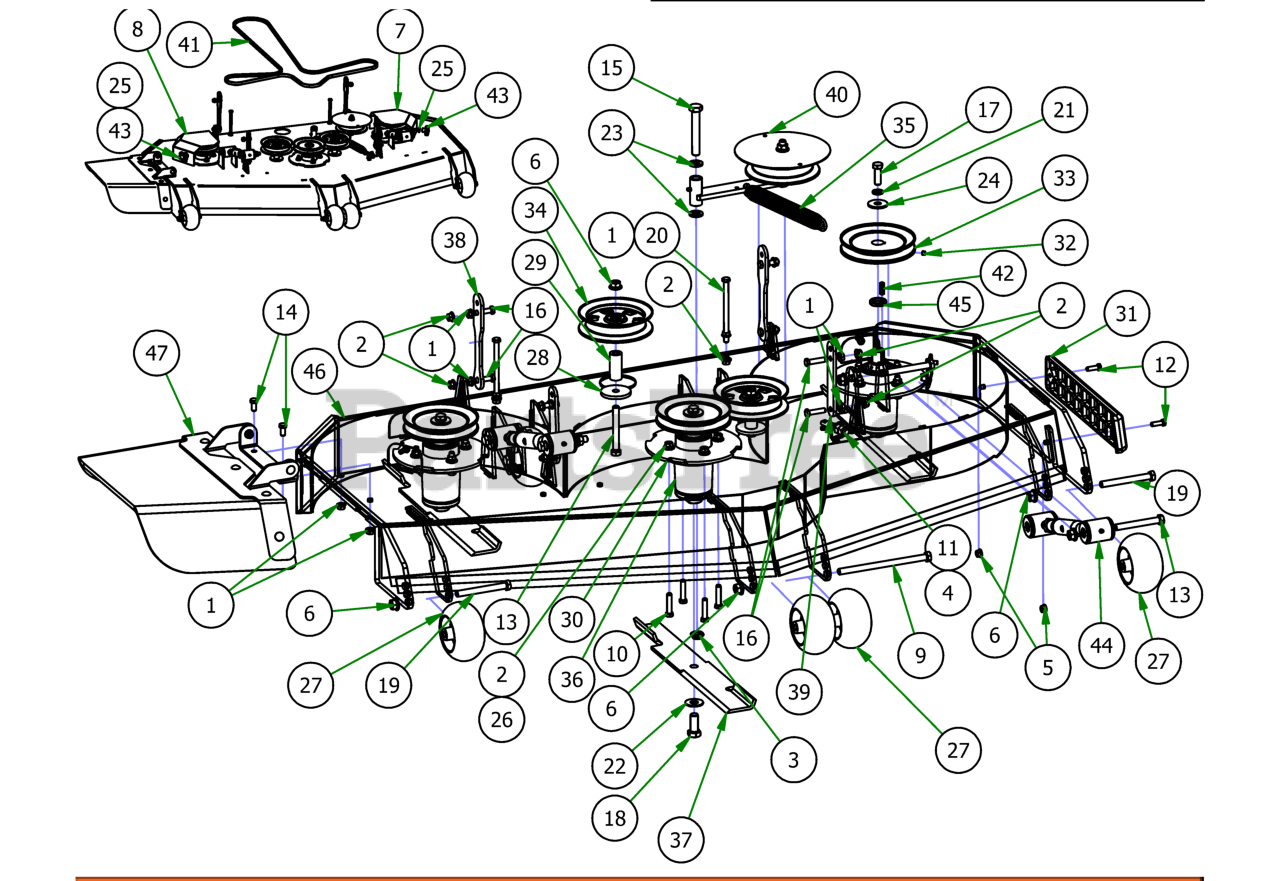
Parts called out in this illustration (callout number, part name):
1	3/8-16 HEX SERRATED FLANGE NUT HARD/ZINC
2	3/8-16 NYLON INSERT FLANGE LOCKNUT (GR.F) ZINC
3	5/8-11 NYLON INSERT JAM LOCKNUT ZINC
4	1/2-13 HEX NUT ZINC
5	5/16-18 NYLON INSERT FLANGE LOCKNUT ZINC
6	1/2-13 NYLON INSERT FLANGE LOCKNUT ZINC
7	2019 Stand On 54" Pulley Cover Trim
8	2019 Stand On 54" Pulley Cover Discharge
9	1/2-13 X 8 HEX CAP SCREW GR 5 ZINC
10	3/8-16 X 1-3/4 HEX C/S (GR.5) ZC
11	All Thread
12	5/16-18 X 1 HEX CAP SCREW (GR.5) ZINC
13	1/2-13 X 4 HEX CAP SCREW (GR.8) ZINC YELLOW
14	3/8-16 X 3/4 HEX CAP SCREW (GR.5) ZINC
15	5/8-11 X 4 HEX CAP SCREW (GR.8) ZINC YELLOW
16	3/8-16 X 1-1/2 HEX CAP SCREW (GR.5) ZINC
17	1/2-20 X 1-1/2 HEX CAP SCREW (GR.5) ZINC
18	5/8-18 X 1-1/2 HEX CAP SCREW (GR.8) ZINC YELLOW
19	1/2-13 X 4-1/2 HEX CAP SCREW (GR.5) ZINC
20	3/8-16 X 5-1/2 HEX CAP SCREW (GR.5) ZINC
21	1/2 SPLIT LOCKWASHER (GR.8) ZINC/YELLOW
22	5/8 USS FLAT WASHER (1-3/4" OD) GR.8 ZINC YELLOW
23	.635 ID X 1.120 OD X .140 THICK FLAT WASHER NYLON
24	1/2 BELLEVILLE WASHER (1-5/8 OD X .140 THK) ZINC
25	.360 ID X .983 OD X .120 THICK FLAT WASHER NYLON
26	5/16 USS FLAT WASHER (7/8 OD) ZINC
27	2019 Deck Wheel
28	MZ Deck Idler Spacer
29	2019 Revolt Stationary Idle Spacer
30	Deck Spindle Support Plate
31	REVISED TRIM BUMPER_20180226
32	5/16-24 X 1/4 SOCKET SET SCREW (CUP PT) PLAIN
33	6 1/4" Drive Pulley
34	5-3/4 Idler Pulley
35	2019 Outlaw Gen2 Deck Spring
36	Spindle Assembly
37	61 inch Fusion Blade
38	2019 Stand-On Rear Deck Hanger
39	2019 Revolt Front Deck Hanger
40	2020 61 Revolt Deck Idler Assembly
42	1/4 X 1 SQ MACHINERY KEY 1018 STL PLN
43	5/16" Knob
44	Turnbuckle
45	Spacer, 1x1.375x.25
46	61" Revolt Deck Weldment-Bad Boy Orange
47	2019 Outlaw Gen2 Chute Assembly
